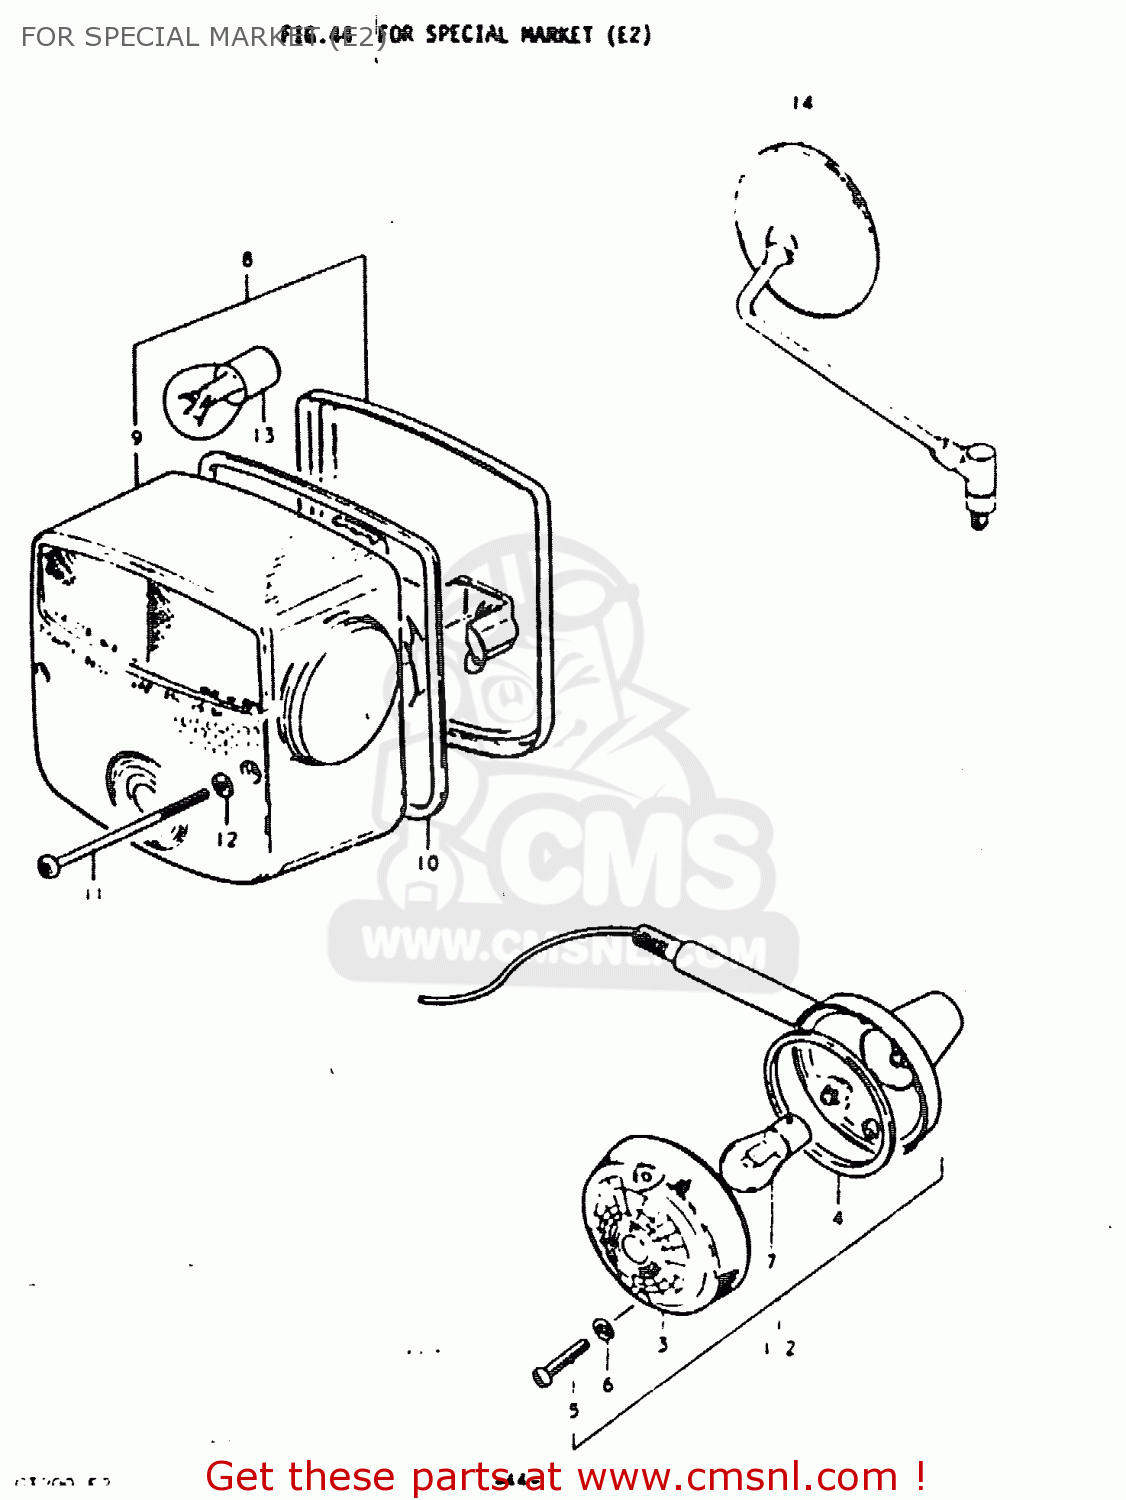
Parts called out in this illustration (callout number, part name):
1	LAMP ASSY, FRONT TURN SIGNAL
2	LAMP ASSY, REAR TURN SIGNAL
3	LENS
4	GASKET (NAS)
5	SCREW
6	GASKET (NAS)
7	BULB 12V 21W
8	LAMP ASSY, REAR COMBINATION
9	LENS
10	GASKET (NAS)
11	SCREW (4X55)
12	GASKET (NAS)
13	BULB 12V21/5W
14	MIRROR ASSY,RH
